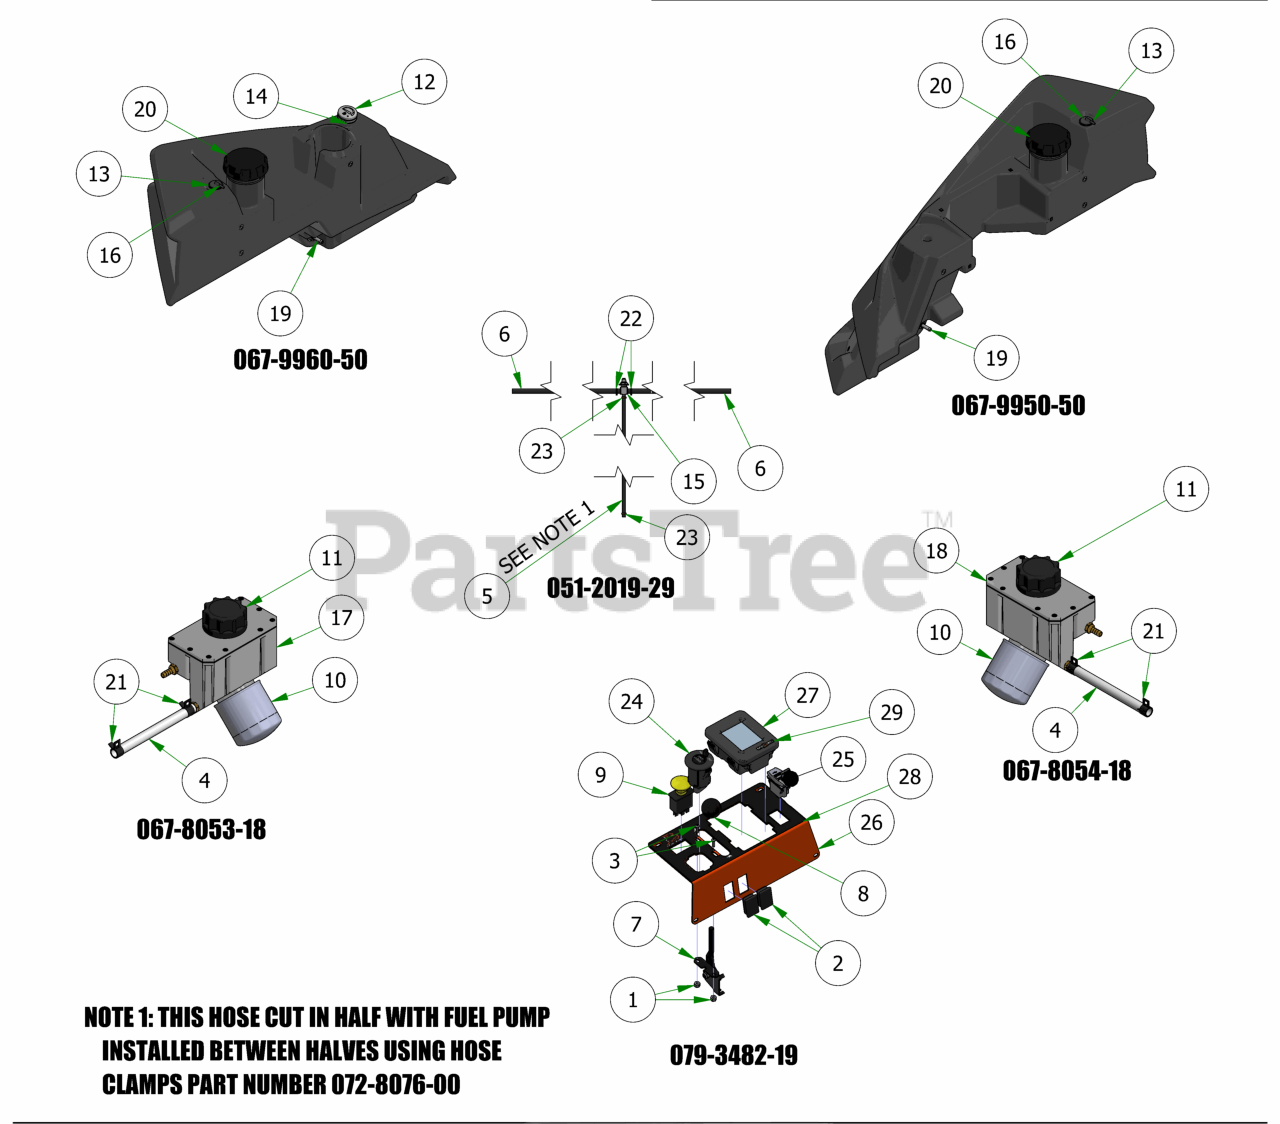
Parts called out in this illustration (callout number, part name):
1	10-24 Nylon Insert Locknut
2	Light Plug
3	10-24 X 5/8 BS Button Head Bolt
4	1/2 Clear Braded Hose 21"
5	1/4" Fuel Line Hose
6	5/16" fuel line hose
7	Universal Throttle Head - 2012
8	Throttle Knob
9	PTO Switch
10	Hydraulic Filter
11	Hydraulic Tank Cap W/Dipstick
12	Fuel Gauge with Grommet
13	Roll Over Valve Grommet
14	Fuel Gauge Grommet
15	3 Way Fuel Shut-Off Valve 5/16 x 5/16 x 1/4
16	Rollover Valve
17	2019 Left Outlaw Gen2 Hydro Tank Suspension Only
18	2019 Right Outlaw Gen2 Hydro Tank Suspension Only
19	Fuel Pick-up
21	1/2 Hose Clamp
22	5/16 Fuel Line Clamp
23	1/4 Fuel Hose Clamp
24	2019 Push to Start Switch w/fob
26	2019 Outlaw Digital Control Panel
27	2019 LED Display
28	2022 Renegade (Gas) Control Panel Decal
29	2022 Digital Display Decal
